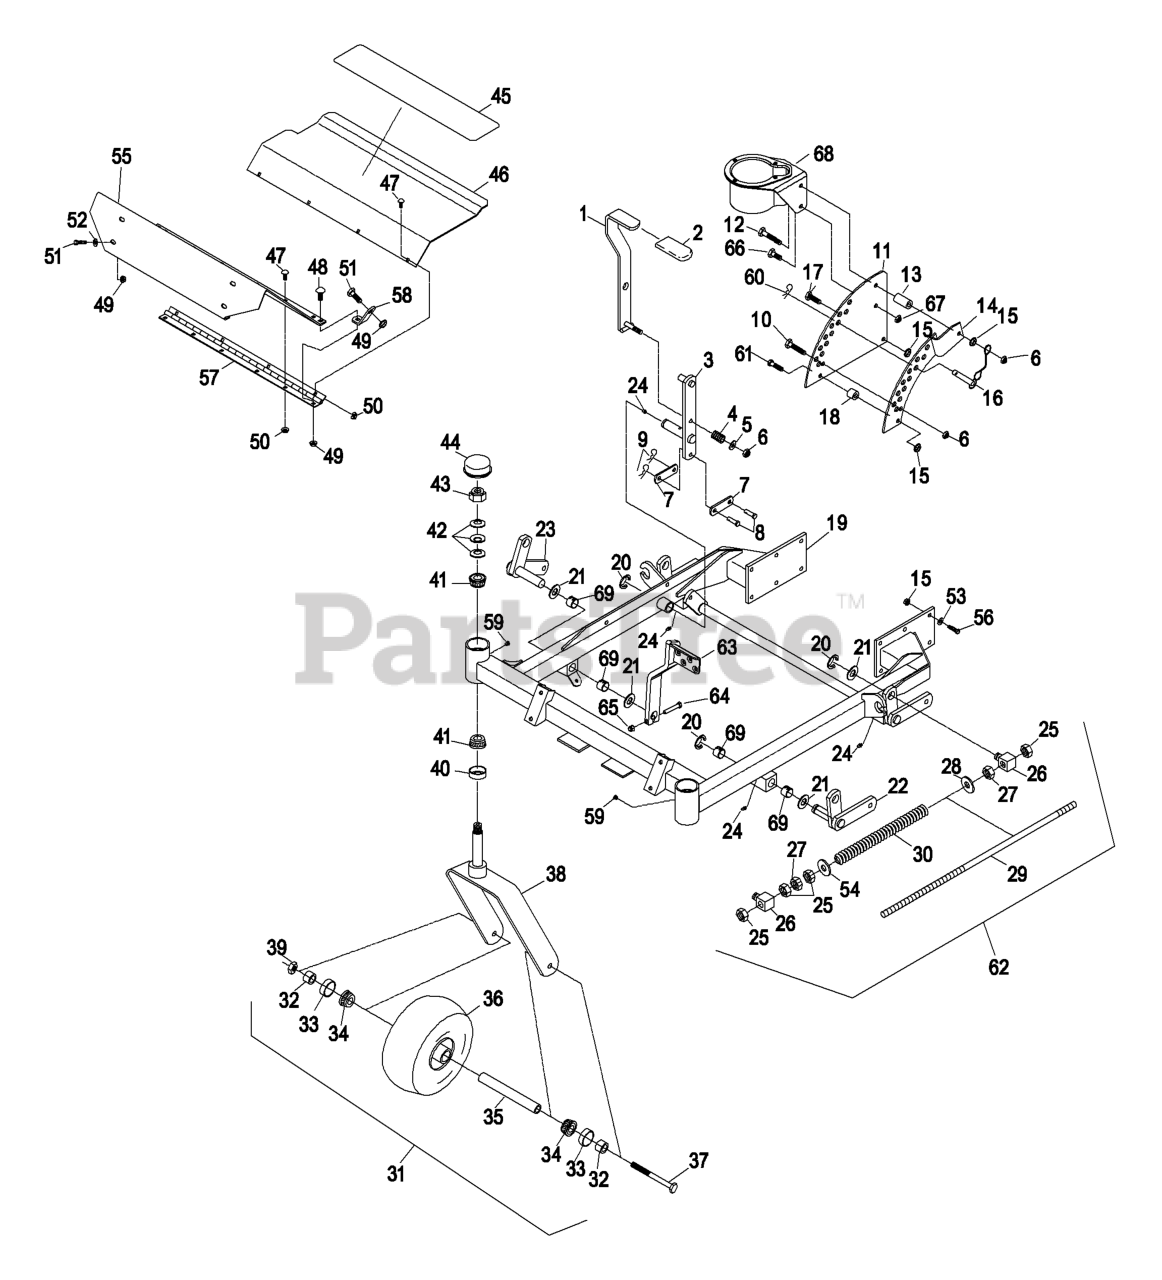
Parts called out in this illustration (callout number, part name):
1	ASM, LIFT LEVER / GRIP
2	GRIP-LEVER, LIFT
3	ARM-DECK, LIFT
4	SPRING-COMPRESSION
5	WASHER-FLAT
6	NUT-LOCK, NI
7	ARM-LIFT, DECK
8	PIN-CLEVIS
9	PIN-COTTER
10	SCREW-HH
11	PLATE-LIFT, DECK
12	SCREW-HH
13	BUSHING-LEVER, LIFT
14	PLATE-LIFT, DECK
15	NUT-HHF, WHIZ
16	PIN-HITCH (W/LANYARD)
17	SCREW-HH
18	BUSHING-LEVER, LIFT
20	RING-RETAINING, EXT
21	WASHER-FLAT
22	WLD,SHAFT LH
23	WLD,SHAFT RH
24	FITTING-GREASE
25	NUT-HEX
26	SWIVEL-DECK MOUNT, REAR
27	NUT-JAM
29	ROD-LIFT, DECK
30	SPRING-COMPRESSION
32	SPACER-BEARING
33	SEAL-CASTER
34	BEARING-CONE, TAPERED ROLLER
35	SPACER-CASTER, FRONT
37	SCREW-HH
39	NUT-HEX
40	SEAL-GREASE
41	Cone-Bearing Tapered Roller
42	WASHER-BELLVILLE
43	NUT-LOCK, NI
44	CAP-GREASE
45	PAD-ANTISKID
47	SCREW-CARR
48	BOLT-CARR
51	SCREW-HH
52	WASHER-FLAT
53	WASHER-BELLEVILLE
54	WASHER-FLAT
56	SCREW-HH
57	HINGE-FLOORPAN
58	BRACKET-FLOORPAN
60	PIN-COTTER
61	SCREW-HH
62	FRONT SPRING ASM
64	Screw, 5/16-18 X 2
65	NUTTORQUE ZKPLT
66	SCREW-HH
69	BUSHING,SPRING
